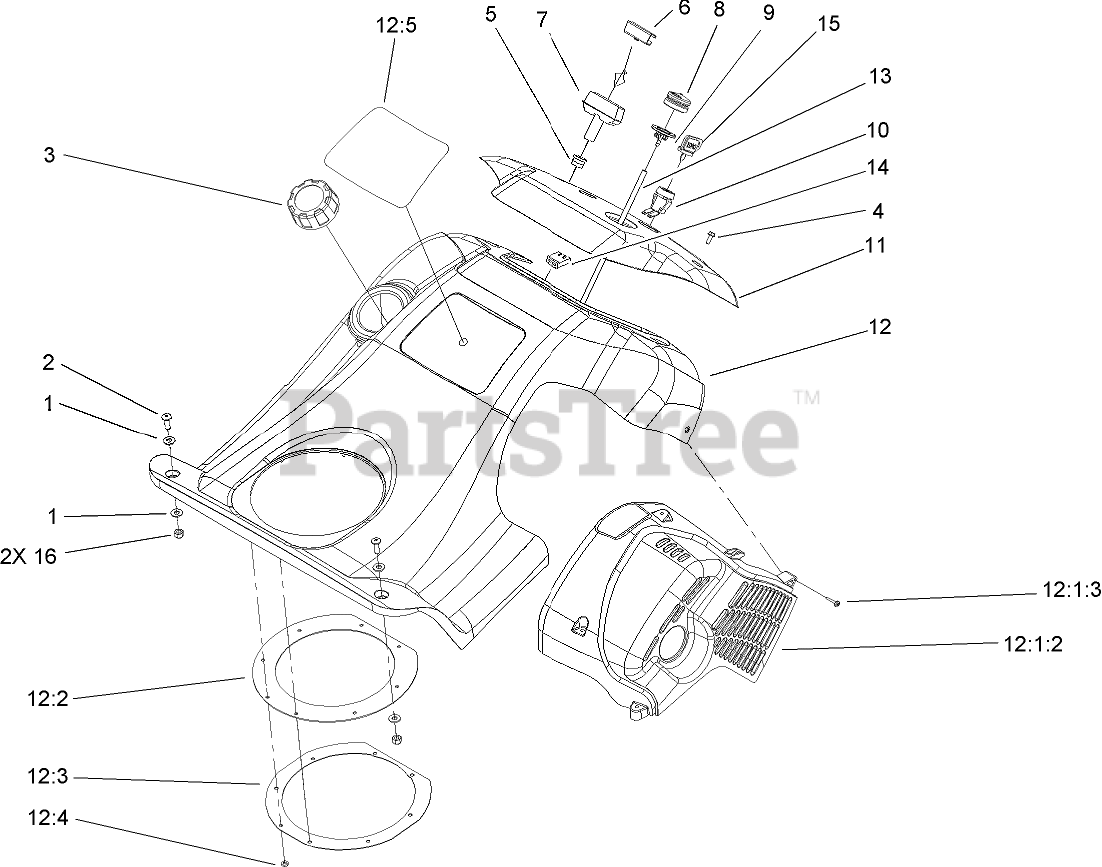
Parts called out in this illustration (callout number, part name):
1	WASHER-FLAT
2	SCREW-PPH
3	GAS CAP ASM
4	SCREW-HWH
5	GUIDE-ROPE, STARTER
6	CLIP-STARTER
7	HANDLE-START
8	BULB-PRIMER
9	BODY-PRIMER
10	SWITCH
11	PANEL-CONTROL ES,CE
12	UPPER SHROUD ASM
12:1:2	SHIELD-HEAT
12:1:3	SCREW-PPH
12:2	Seal-Chute
12:3	RETAINER-SEAL, CHUTE
12:4	PALNUT
12:5	DECAL-SHROUD, ELECTRIC START
13	HOSE-PRIMER
14	CONNECTOR-BODY
15	KEY-IGNITION
16	NUT-LOCK, NI
